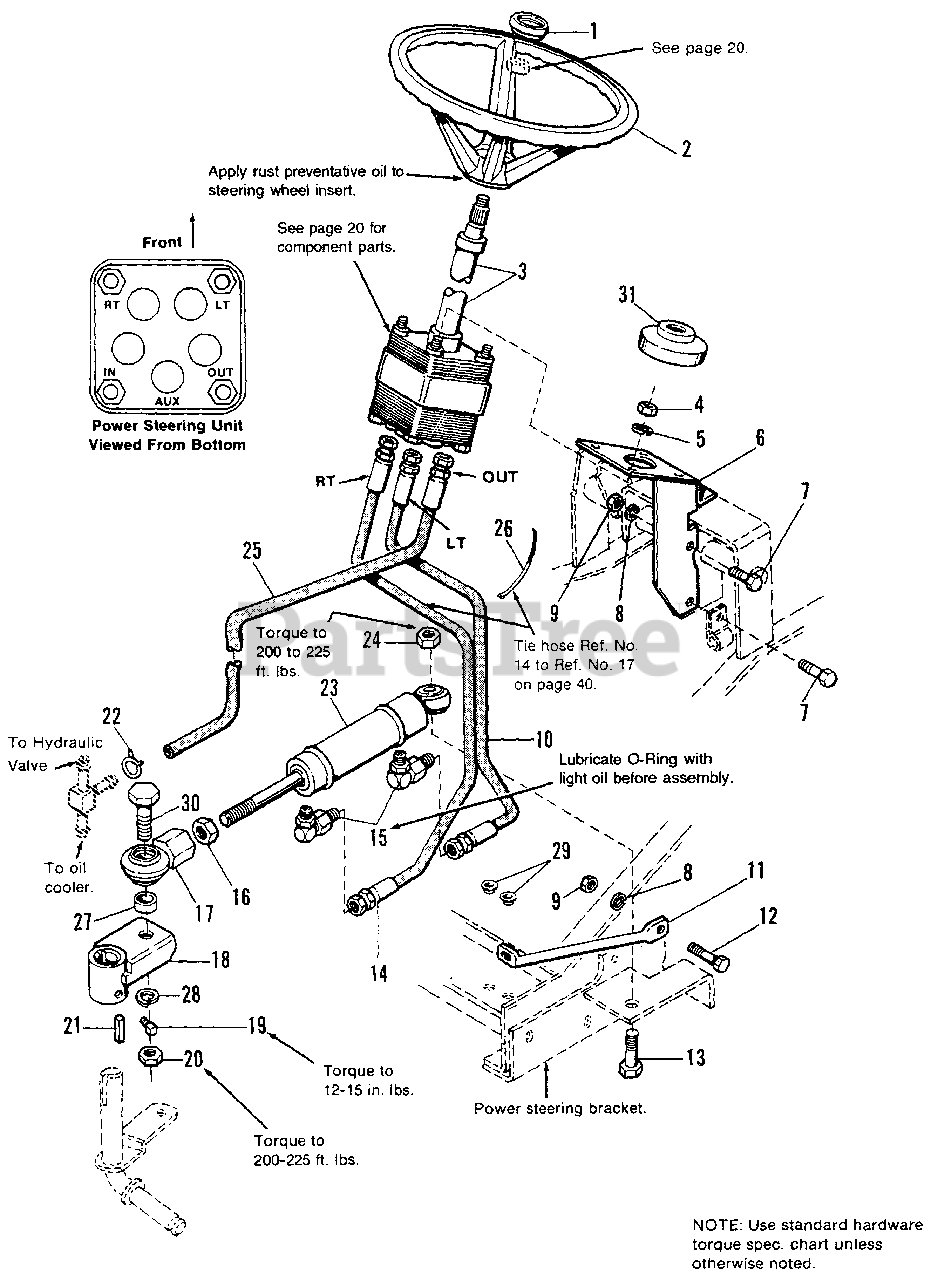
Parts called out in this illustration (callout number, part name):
1	CAP, Steering Wheel
2	WHEEL ASSY., Steering
3	STEERING UNIT, Hydrostatic (See page 20 for components.)
4	NUT, Hex, 5/16-24
5	LOCKWASHER, 6/16
6	SUPPORT ASSY., Steering Valve
7	CAPSCREW, Hex Hd., 3/8-16 x 1, Gr. 5
8	LOCKWASHER, 3/8
9	NUT, Hex, 3/8-16
10	HOSE ASSY., Hyd. (Valve to Cyl.)
11	BRACE, Cylinder
12	CAPSCREW, Hex Hd., 3/8-16 x 1-1/2, Gr. 5
13	CAPSCREW, Hex Hd., 5/8-11 x 2, Gr. 8
14	HOSE ASSY., Hyd. (Valve to Cyl.)
15	FITTING, Hyd., 9/16-18 x 9/16-18 - 90
16	NUT, Hex, 3/4-16
17	BALL JOINT ASSY. (Inc. Ref. Nos. 20, 27, 28 & 30)
18	ARM ASSY., Steering
19	SETSCREW, Sq. Hd., 5/16-18 x 1/2
20	NUT, Hex, Lock, 3/4-16
21	KEY, Parallel, 1/4 x 1/4 x 1-1/2
22	HOSE CLAMP, SAE #10
23	CYLINDER, Power Steering
24	LOCKNUT, Hex, 5/8-11
25	HOSE ASSY., Hyd., (Valve to Cooler)
26	TIE, Self-Locking
27	SPACER
28	LOCKWASHER 3/4
29	PLUG, Plastic
30	CAPSCREW, Hex Hd., 3/4-16 x 2-3/4, Gr. 5
31	BOOT, Steering Arm
